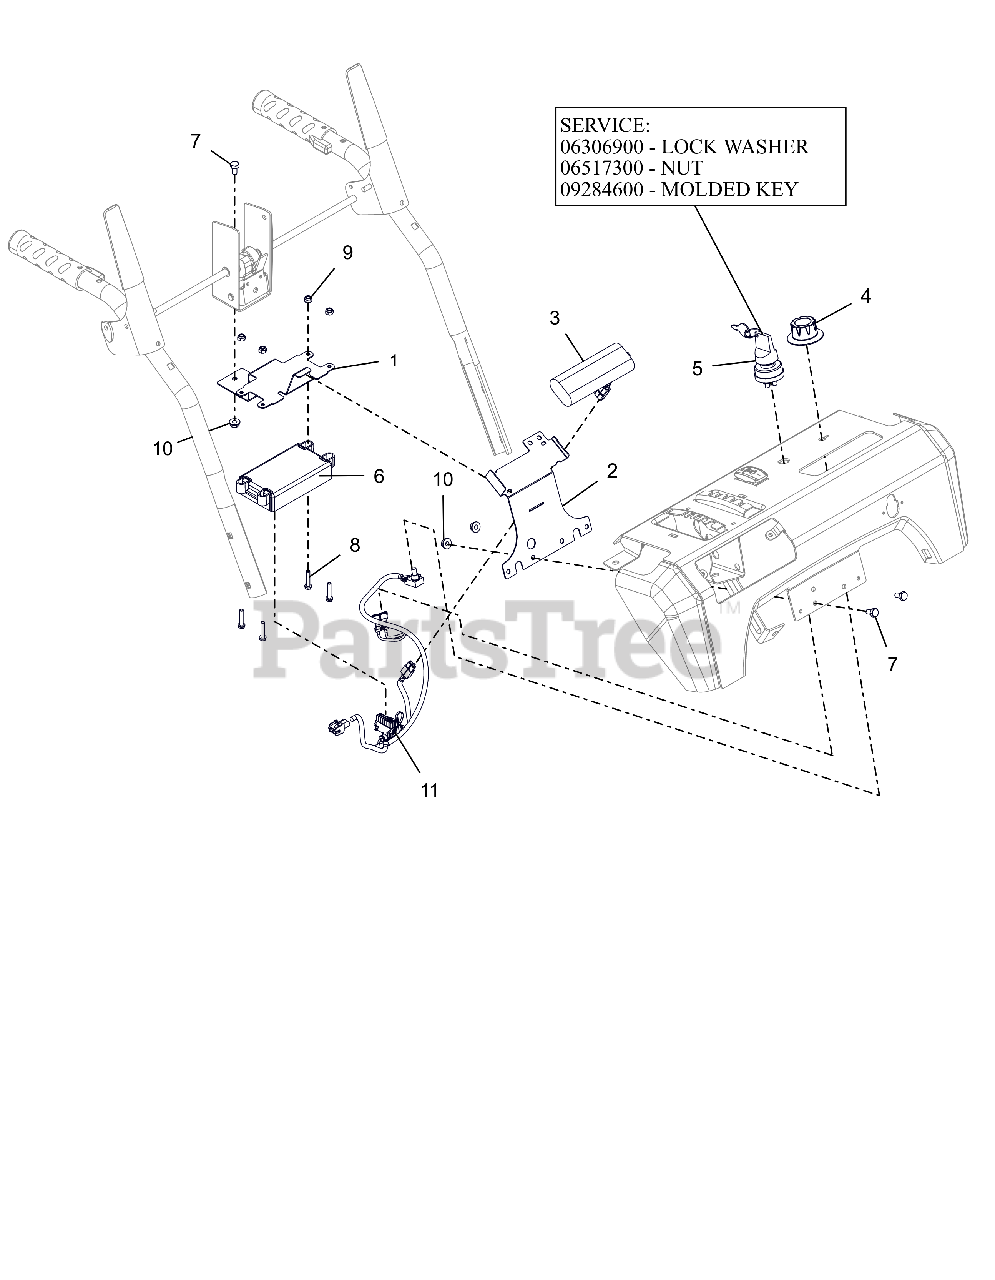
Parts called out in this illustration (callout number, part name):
1	BRACKET, ENGINE EFI-LCT LOWER
2	BRACKET, ENGINE EFI-LCT UPPER
3	BATTERY, SNOW EFI - 7.2V
4	KNOB, CONTROL - 2.063 ID
5	IGNITION SWITCH ASM - 2 POS
5	WSHR-LK-INT .625X.045 YWZC
5	NUT-PANEL .625-32 GRECO
5	KEY W/ SHIELD
6	ECU, AX369 EFI
7	BLT,HEX .25-20X.50 G5 ZCC
8	BLT, HWH #10-24X1.00 ZCC
9	NUT-LK-NYL #10-24 G2 ZCC
10	NUT-LK-TOP-FLG .250-20 GF ZCC
11	HARNESS,WIRE - EFI ECU
